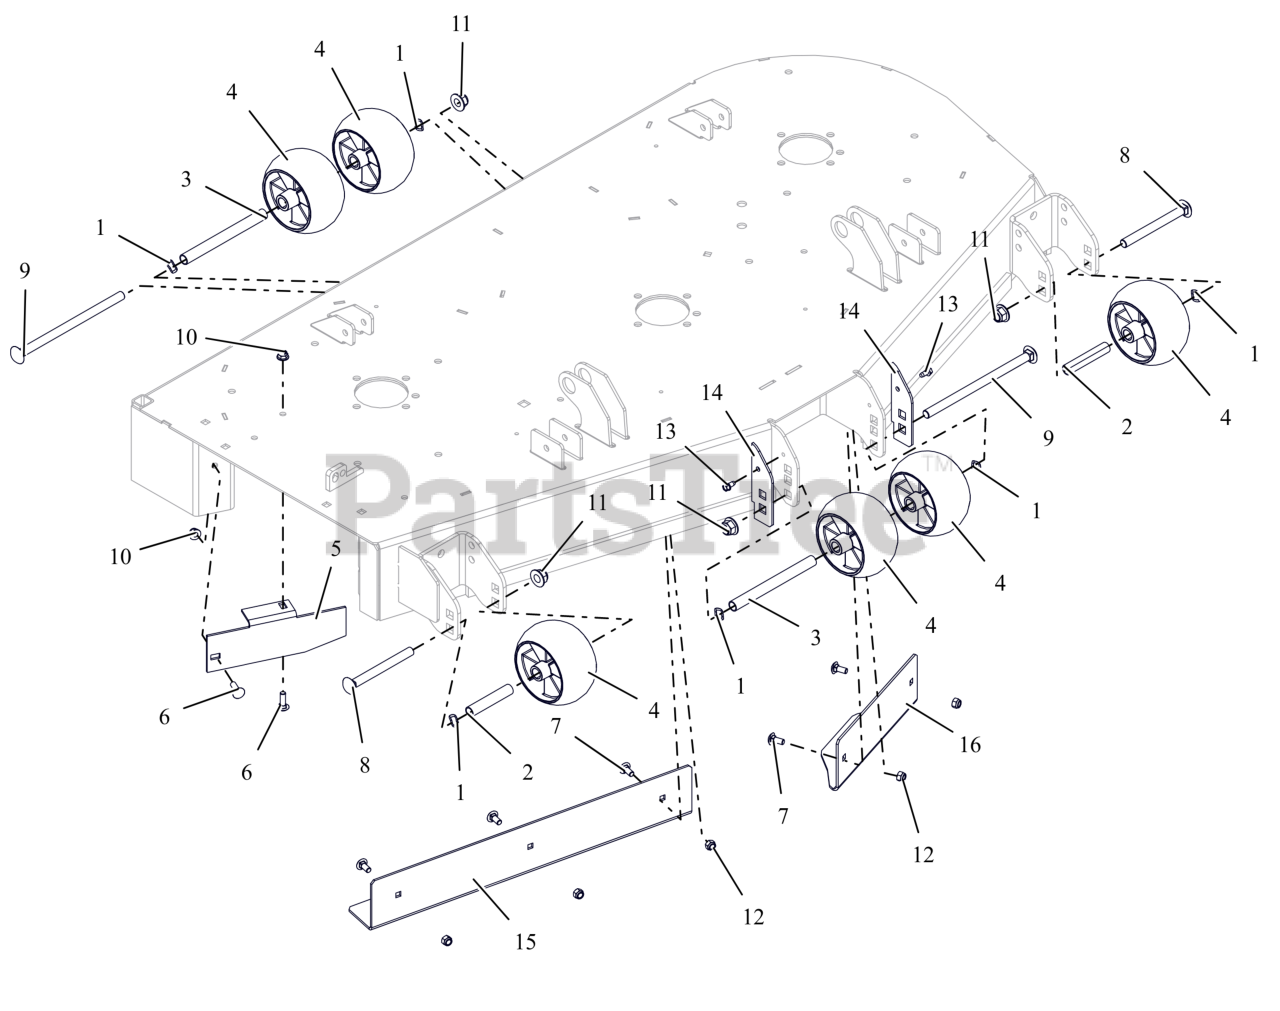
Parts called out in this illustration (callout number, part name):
1	WAVE WASHER .531X.781X.125FH
2	SPACER, .510X.625X3.35
3	SPACER, .510X.625X6.50
4	ANTI-SCALP WHEEL - 5X3 CTR
5	BAFFLE, DISCHARGE, 52"
6	BLT,RHSN .31-18X1.00 G5 ZCC
7	BLT,RHSN .31-18X.75 G5 ZCC
8	BLT, RHSN .50-13X5.00 G5 ZCC
9	BLT, RHSN .50-13X8.50 G5 ZCC
10	NUT,LK-NYL-FLG .31-18 G5ZC120
11	NUT,NYL-FLG .50-13 GF ZCC
12	NUT,NYL .31-18 G5 ZCC
13	SCR-TAP .25-20X.50 HWH ZCC
14	PLATE, ANTI SCALP WHEEL PLATE CE (ORANGE)
15	BAFFLE, 52" RH VACUUM (ORANGE)
16	BAFFLE, 52" LH VACUUM
